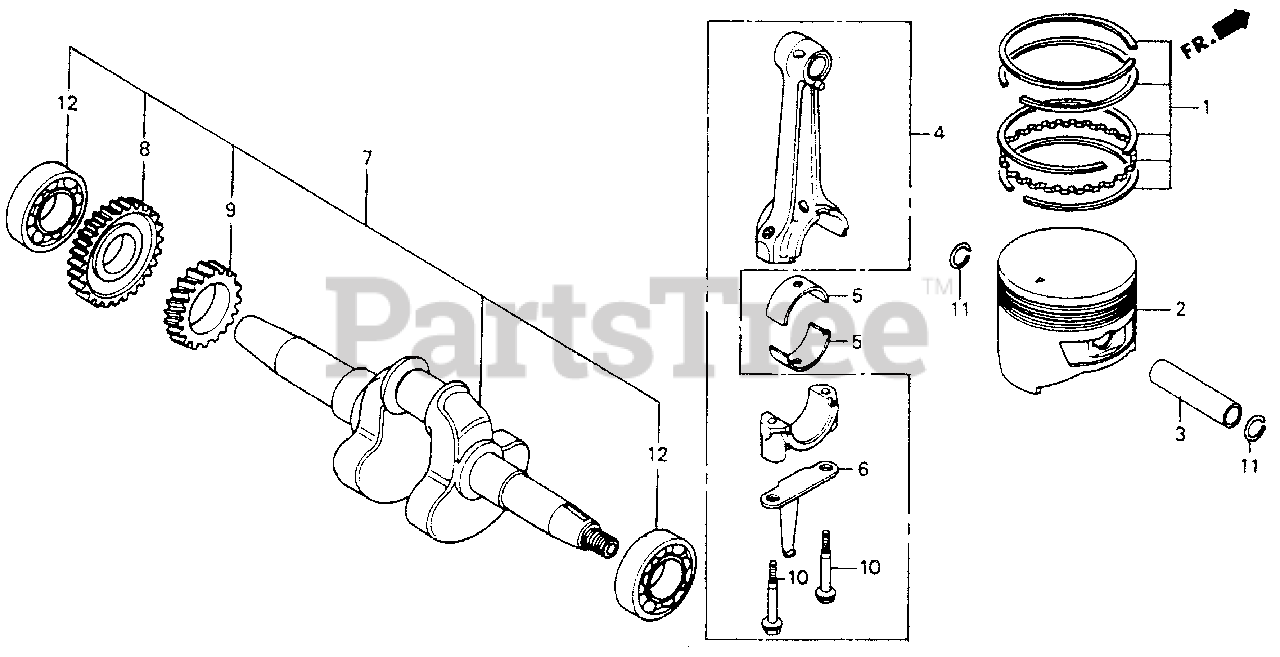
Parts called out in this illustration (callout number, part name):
1	RING SET, PISTON (STD)
1	RING SET, PISTON (STD) (NOT AVAILABLE)
1	RING SET, PISTON (OS 0.25)
1	RING, PISTON (OS 0.50)
1	RING SET, PISTON (OS 0.50)
1	RING SET, PISTON (0.75)
2	PISTON (STD) (NOT AVAILABLE)
2	PISTON (OS 0.25)
2	PISTON (OS 0.50)
2	PISTON (0.75)
3	PIN, PISTON
4	ROD ASSY., CONNECTING
5	BEARING A, CONNECTING ROD
5	BEARING B, CONNECTING ROD
5	BEARING C, CONNECTING ROD
5	BEARING D, CONNECTING ROD
5	BEARING E, CONNECTING ROD
6	DIPPER, CONNECTING ROD
7	CRANKSHAFT (NOT AVAILABLE)
8	GEAR, BALANCER
9	GEAR, TIMING
10	BOLT, CONNECTING ROD (8MM)
11	CLIP, PISTON PIN (19MM)
12	BEARING, RADIAL BALL (6206)
